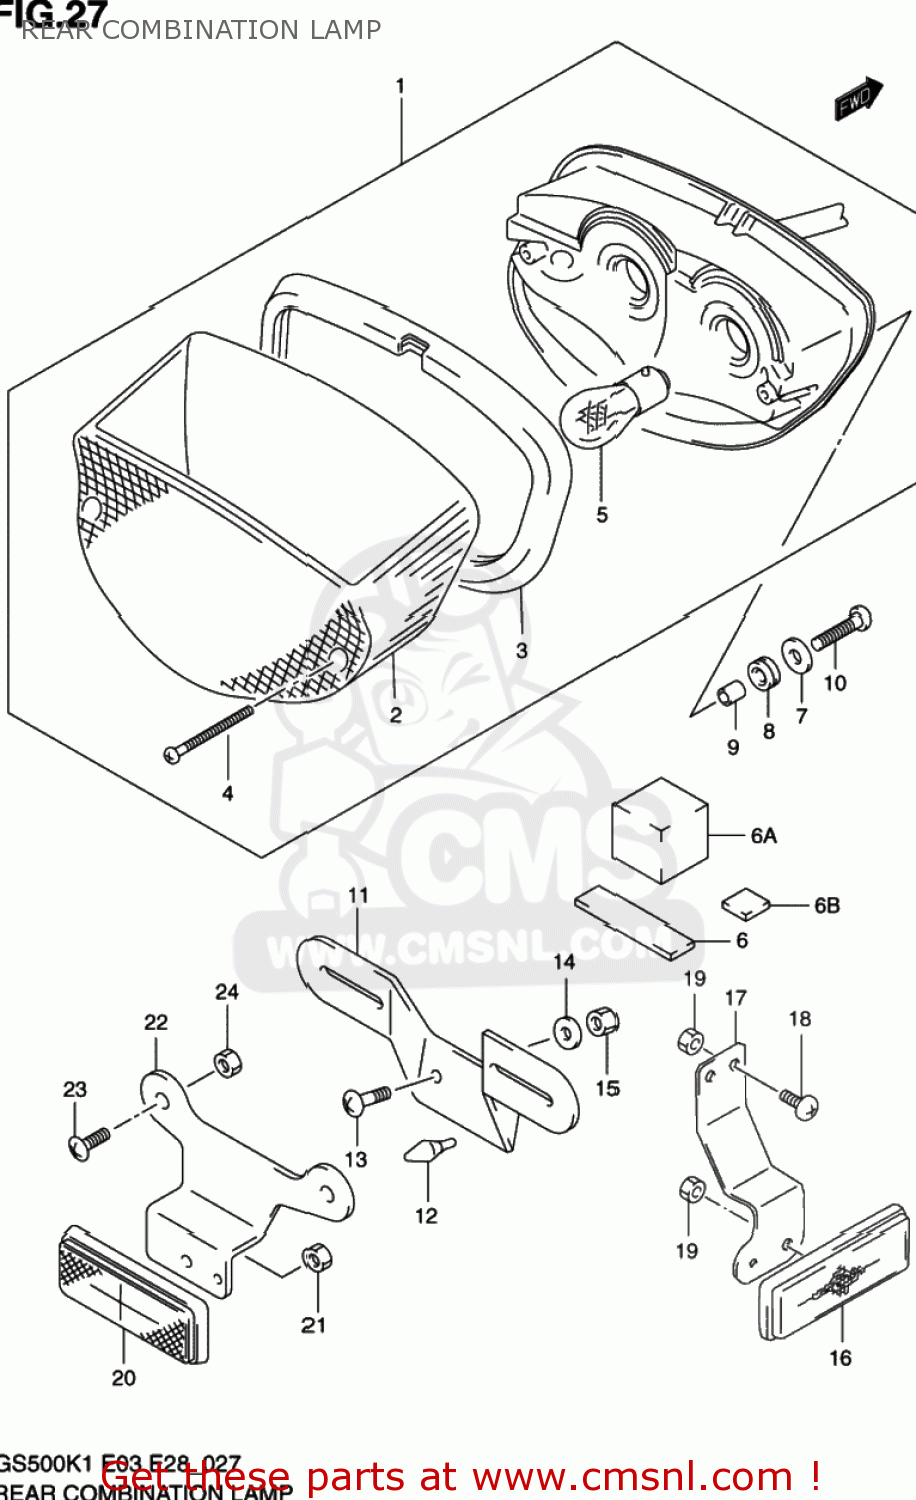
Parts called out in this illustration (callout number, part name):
1	LAMP ASSY,RR COMBINATION
2	LENS
3	GASKET,LENS (NAS)
4	SCREW
5	BULB(12V32/3CP)
6	CUSHION(40X40X40)
6A	CUSHION(40X40X38)
6B	PROTECTOR(40X120X6)
7	WASHER(6.5X20X1.2)
8	CUSHION
9	SPACER(6.5X9X8.5)
10	SCREW, 6X20
11	BRACKET,LICENSE PLATE
12	CUSHION
13	SCREW
14	WASHER(6.5X20X1.2)
15	NUT 6MM
16	REFLECTOR ASSY,RR
17	BRACKET,RR SIDE REFLECTOR
18	SCREW 5X12
19	NUT
20	REFLECTOR ASSEMBLY,REAR
21	NUT
22	BRACKET,RR RR
23	SCREW 6X12
24	NUT 6MM
